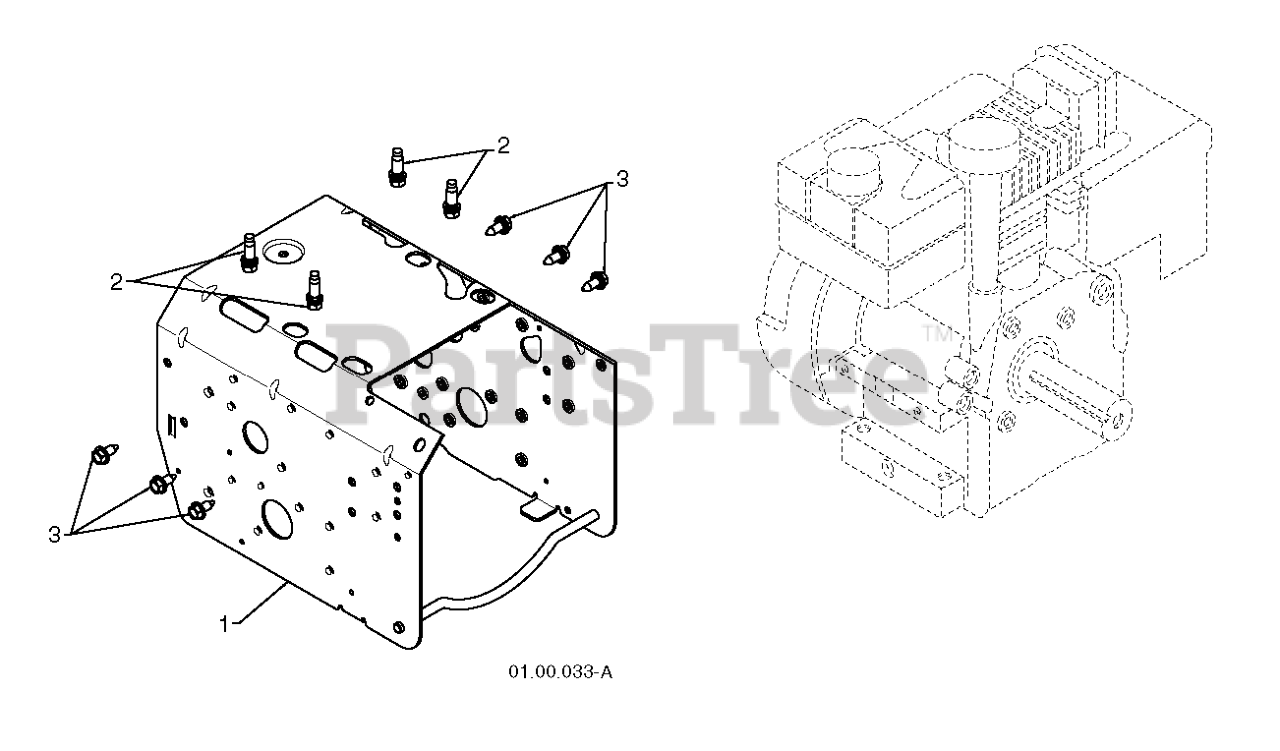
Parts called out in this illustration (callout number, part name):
1	FRAME.WELD.PNT.GEAR.ORANGE
2	BOLT 3/8-16X1-1/8
3	BOLT.HEX.HD.WASHER.5/16-18X.75
